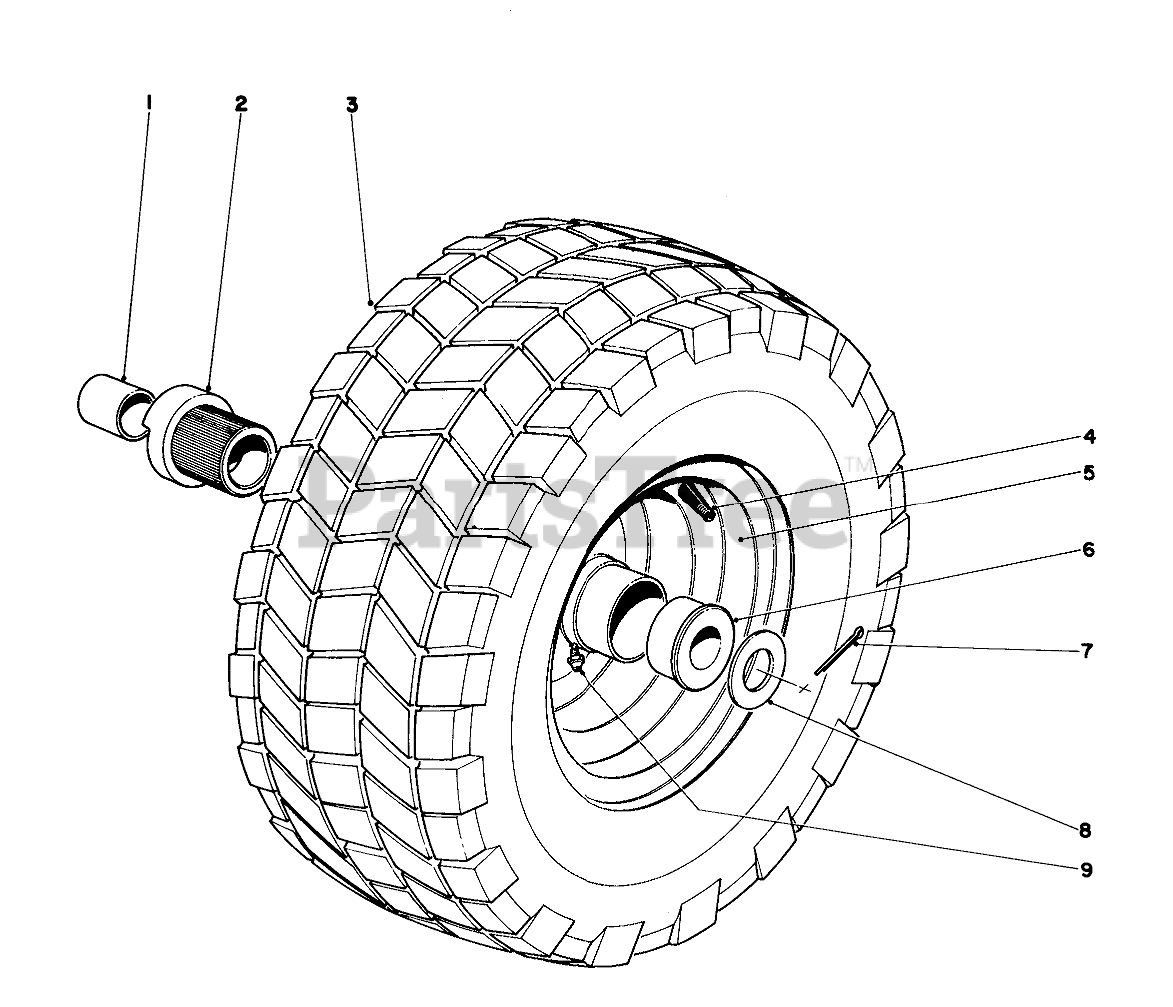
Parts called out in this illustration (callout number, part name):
1	BUSHING
2	Hub Jaw
3	Tire
4	STEM-VALVE
5	Wheel Rim
6	Bushing
7	PIN-COTTER
8	WASHER-THRUST
9	FITTING-GREASE
